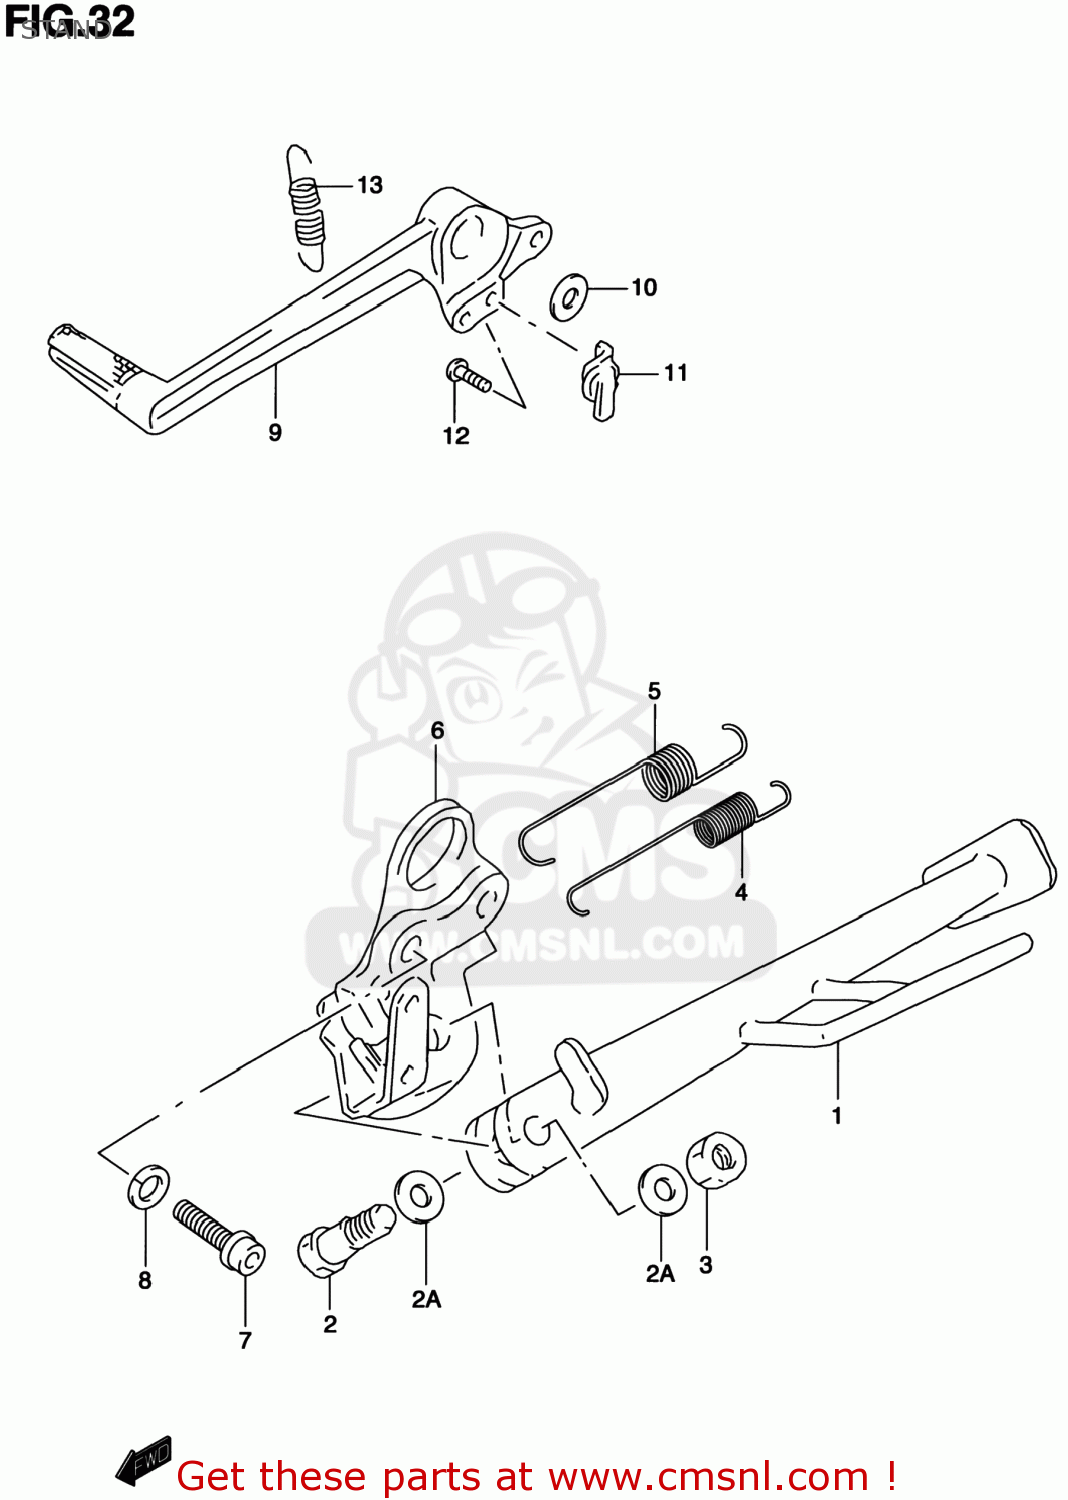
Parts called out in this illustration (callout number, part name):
1	STAND,PROP
2	BOLT(10X34)
2A	WASHER
3	NUT
4	SPRING
5	SPRING
6	BRACKET,PROP STAND
7	BOLT
8	LOCK WASHER
9	PEDAL,BRAKE
10	WASHER(18X24X1)
11	HOOK,RETURN SPRING
12	SCREW
13	SPRING
